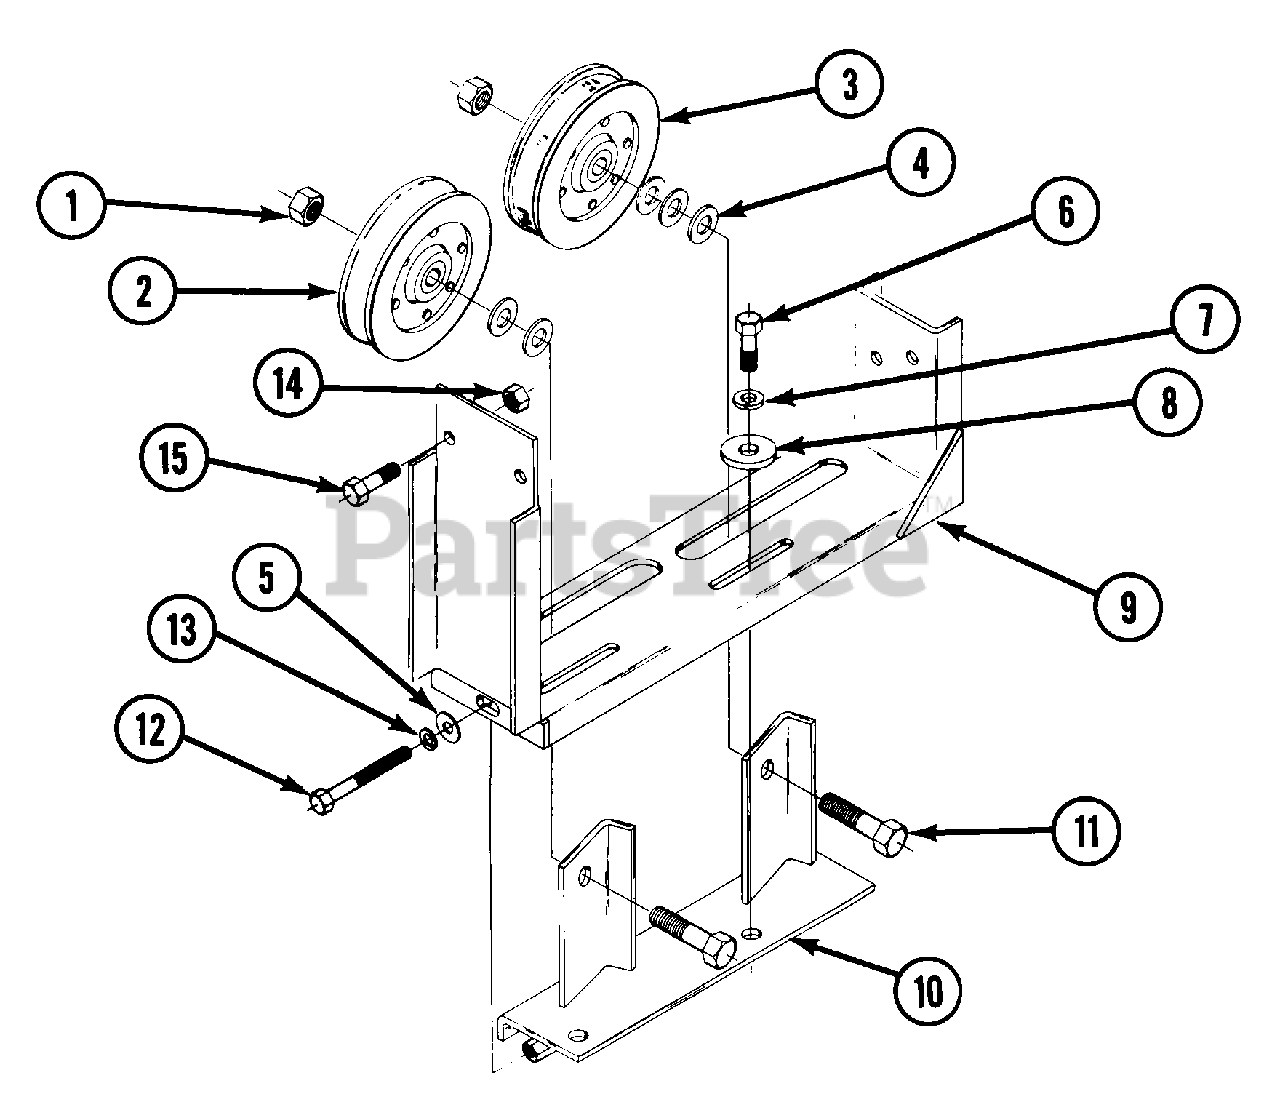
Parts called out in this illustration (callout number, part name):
1	LOCKNUT, HEX, 1/2-13, W/NYLOC
2	IDLER PULLEY, V, 4-3/8 OD, 1/2 BORE
3	FLAT IDLER
4	WASHER, 1/2 STD, FLAT
5	WASHER, 5/16 STD, FLAT
6	CAPSCREW, HEX, 3/8-16 X 1, GRADE 5
7	LOCKWASHER, 3/8 HEAVY, SPLIT SPRING
8	WASHER, .406 ID X 1.25 OD X .168 THK
9	MULE DRIVE IDLER MOUNT WELDMENT
10	SLIDE PLATE WELDMENT
11	CAPSCREW, HEX, 1/2-13 X 2, GRADE 5
12	CAPSCREW, HEX, 5/16-18 X 2-1/2 GRADE 5
13	LOCKWASHER, 5/16 HEAVY, SPLIT SPRING
14	LOCKNUT, HEX, 3/8-16, W/NYLOC
15	CAPSCREW, HEX, 3/8-16 X 1, GRADE 5
